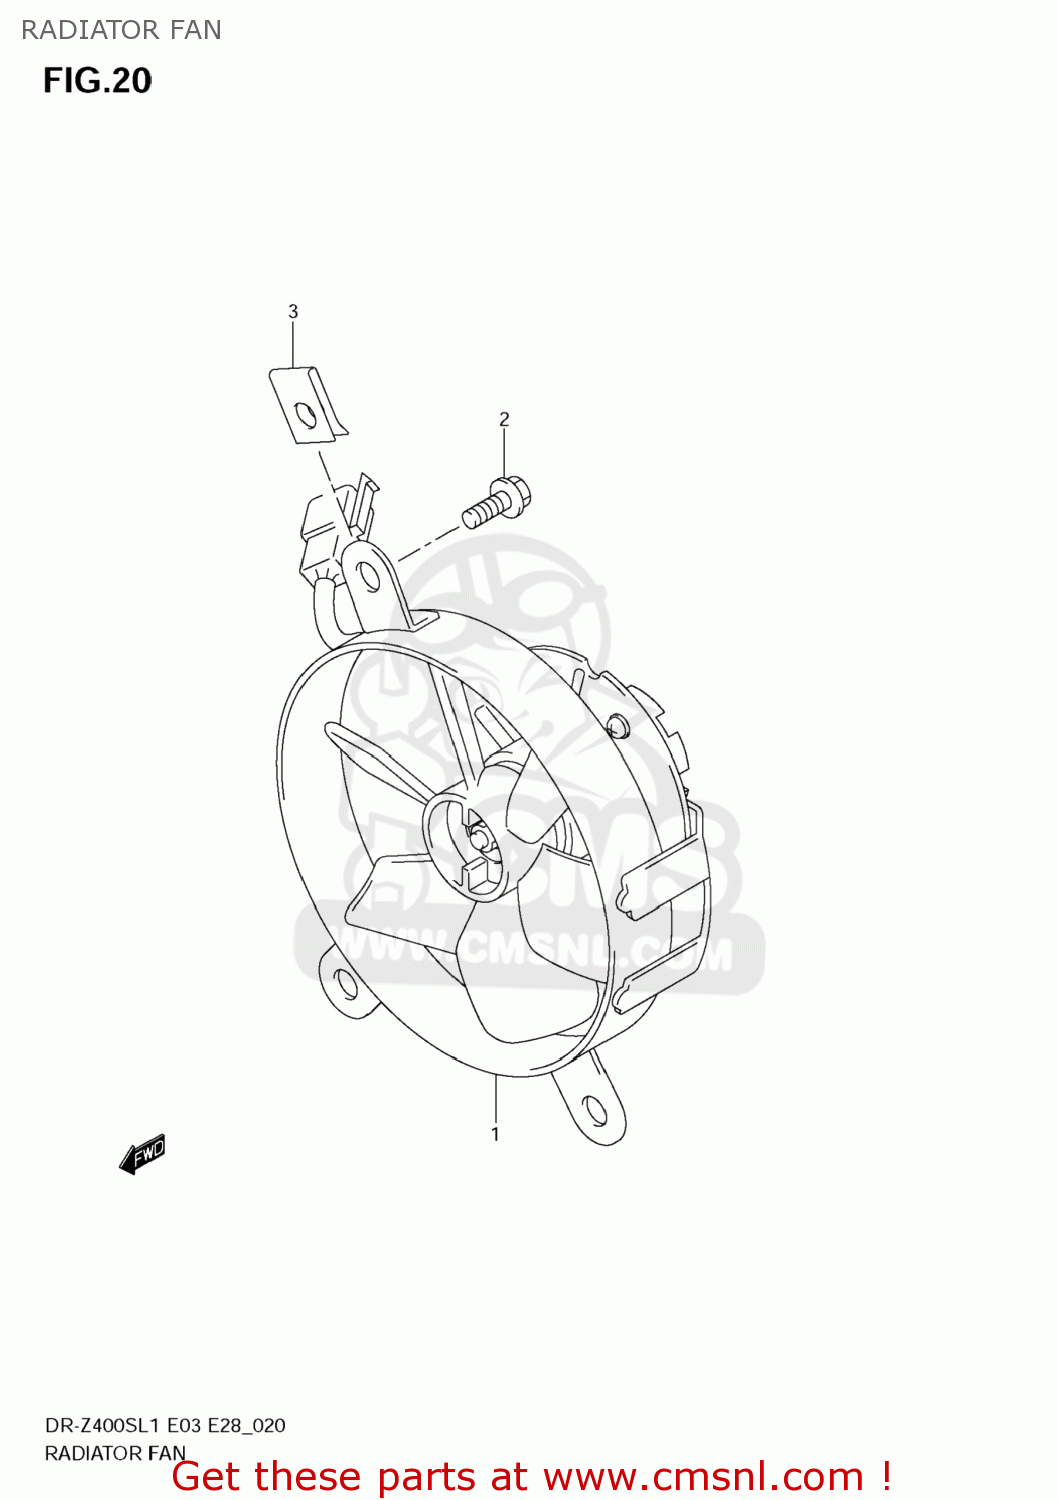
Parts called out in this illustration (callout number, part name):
1	FAN ASSY,RADIATOR
2	BOLT
3	NUT
